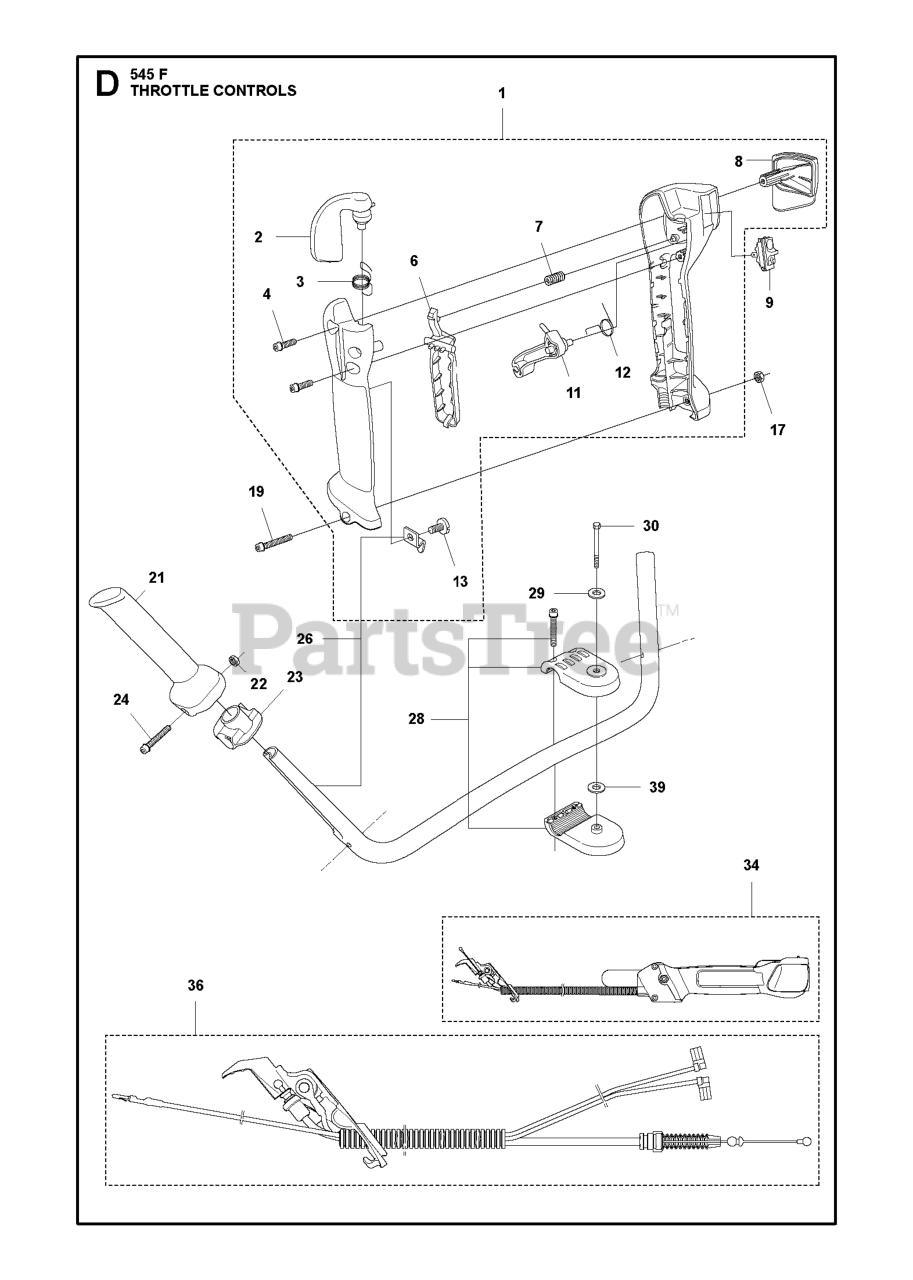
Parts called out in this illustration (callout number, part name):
1	THROTTLE HANDLE
2	THROTTLE TRIGGER
6	THROTTLE LOCK
9	STOP BUTTON
17	NUT M6M M5
19	SCREW IHSCFM
22	NUT M6M M5
26	KIT
28	HANDLEBAR BRACKET KIT
30	SCREW EHHM
34	THROTTLE HANDLE ASSY HVA
36	WIRING ASSY
